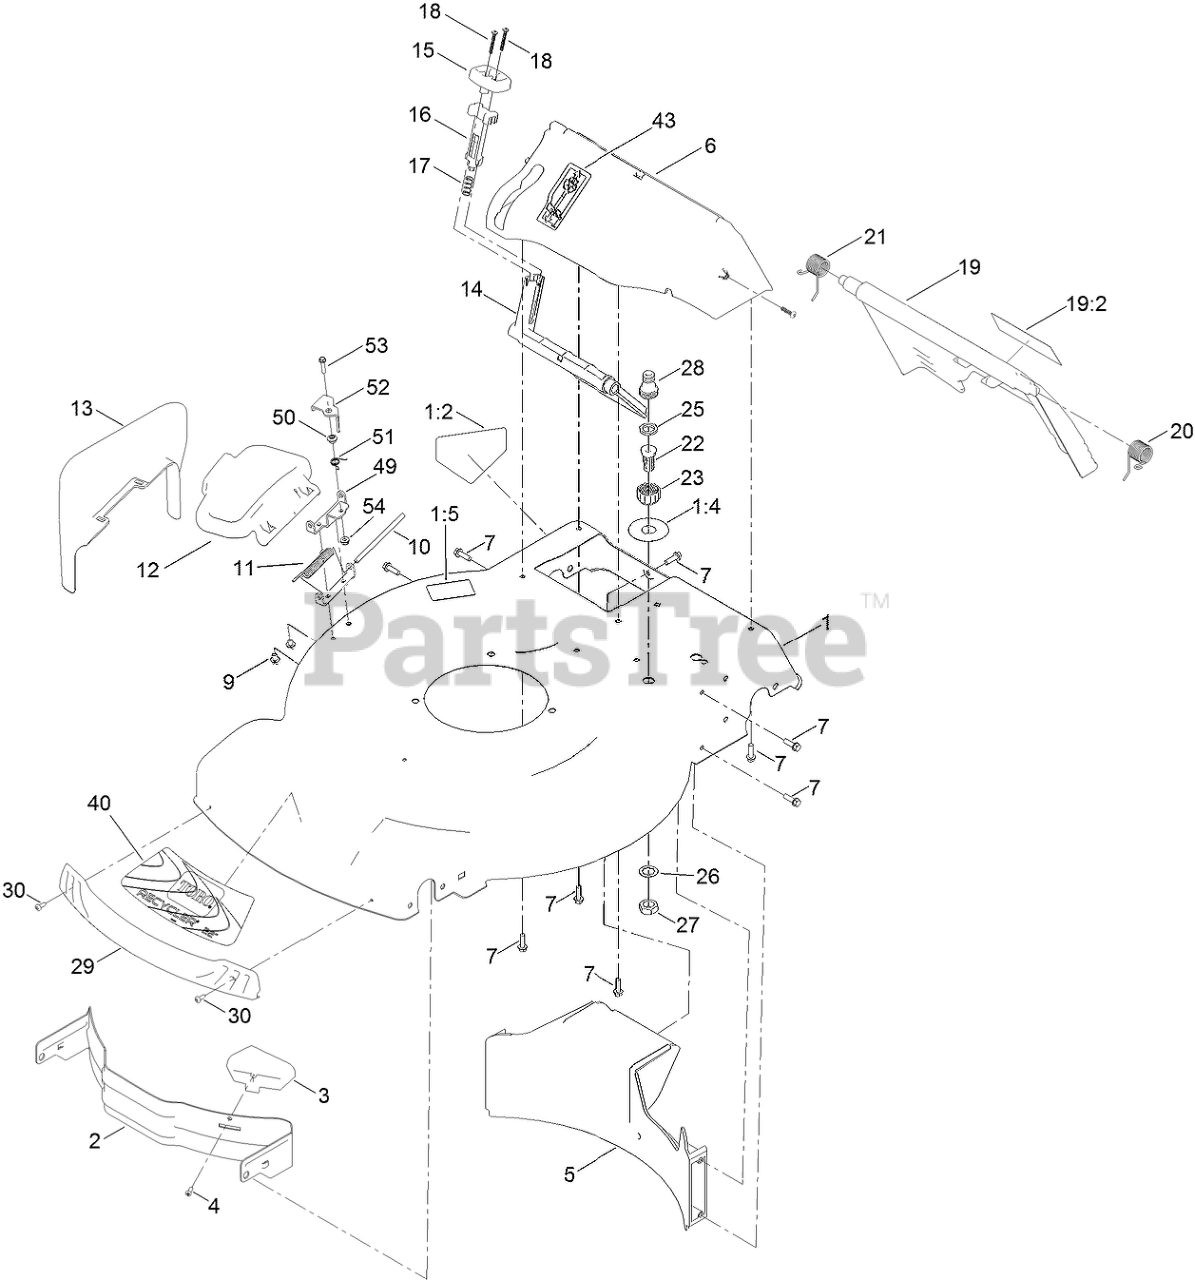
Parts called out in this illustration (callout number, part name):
1	HOUSING ASM
1:2	DECAL-DANGER
1:4	DECAL-QUICK WASH
1:5	DECAL-PLACEMENT, FOOT
2	BAFFLE-FRONT
3	KICKER-FRONT
4	SCREW-PLASTIC, PPH
5	BAFFLE-REAR
6	CHUTE-RECYCLE, ES
7	SCREW-PLASTITE, HWH
11	SPRING-TORSION
12	DEFLECTOR-DISCHARGE, SIDE
13	CHUTE-DISCHARGE, SIDE
14	DEFLECTOR-RECYCLE
15	KNOB-RECYCLE
16	LATCH-RECYCLE
17	SPRING-COMPRESSION
18	SCREW-PPH
19	REAR DOOR ASM
19:2	DECAL-WARNING
20	SPRING-TORSION
21	SPRING-TORSION
22	PORT-WASHOUT
23	COUPLING-HOSE, WASHOUT PORT
25	WASHER-SEAL, WASHOUT PORT
26	WASHER-LOCK, INT TOOTH
27	NUT-JAM
28	ADAPTER-CONNECT, QUICK
29	BUMPER
30	SCREW-FORMING, THREAD
49	BRACKET-LOCKOUT
50	SPACER
51	SPRING-TORSION
52	LEVER-LOCKOUT
53	SCREW-HWH
54	NUT-HEX FLANGE
